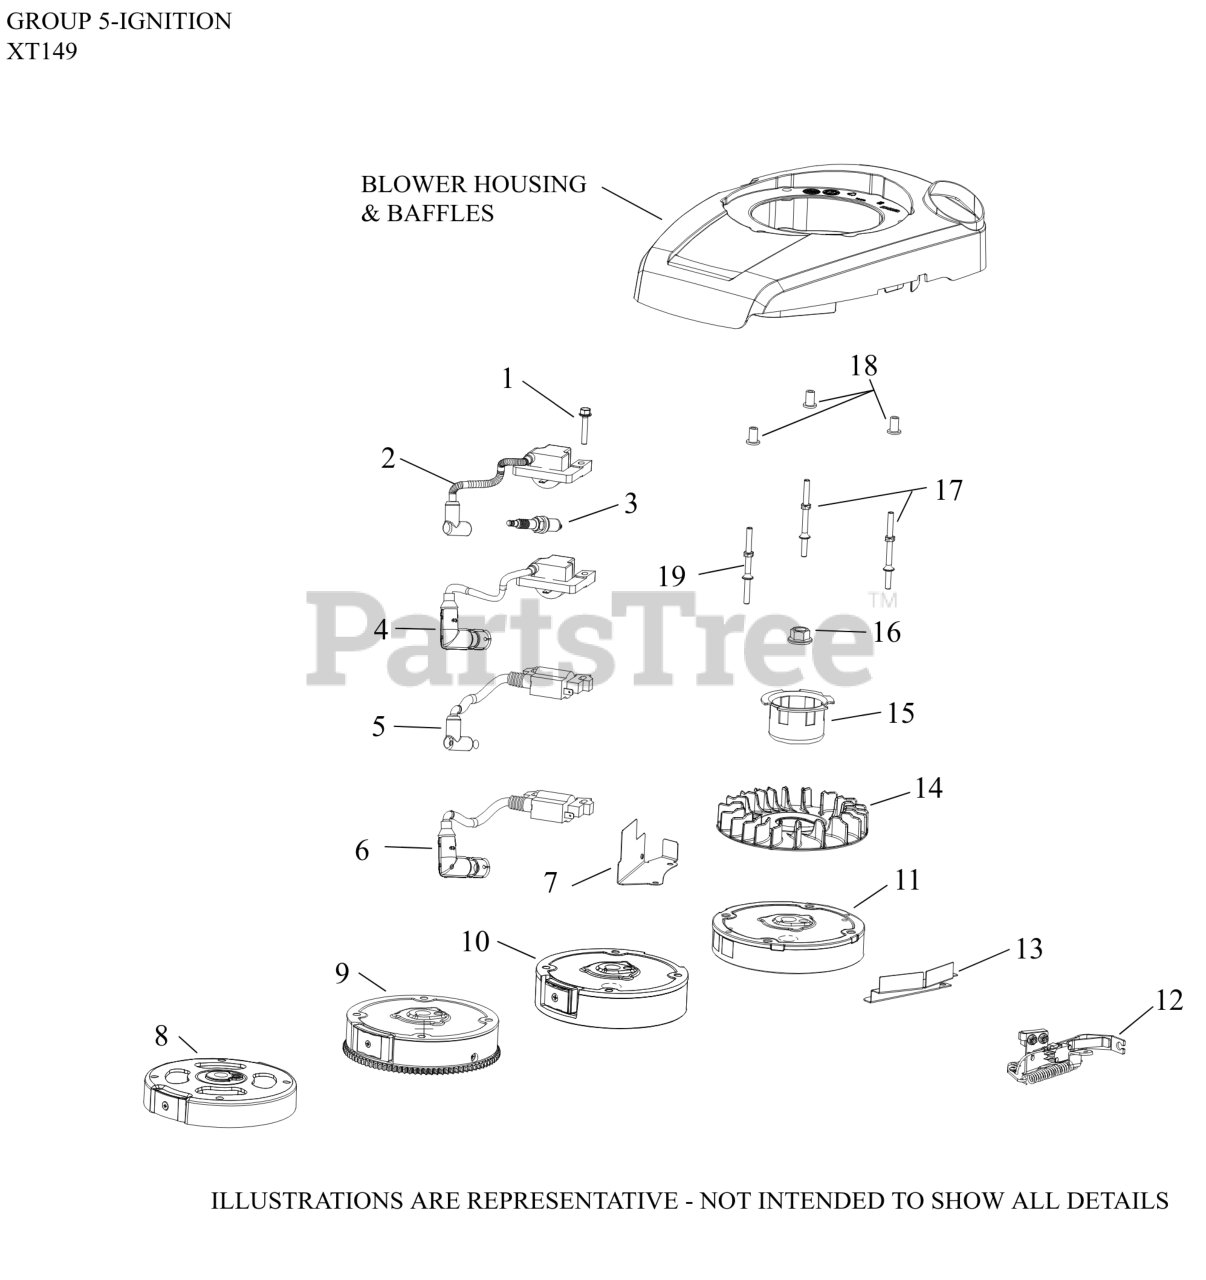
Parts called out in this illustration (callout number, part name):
2	MODULE, IGN (ALUM STD IGN)
3	PLUG, SPARK-USE 14 132 11-S
11	FLYWHEEL ASSEMBLY (ALUMINUM)
12	BRAKE ASSEMBLY, CARB SIDE
14	FAN, FLYWHEEL-(#1715706S)
15	CUP, DRIVE - (#1410905S)
16	NUT, FLYWHEEL (W/SERRATIONS)
